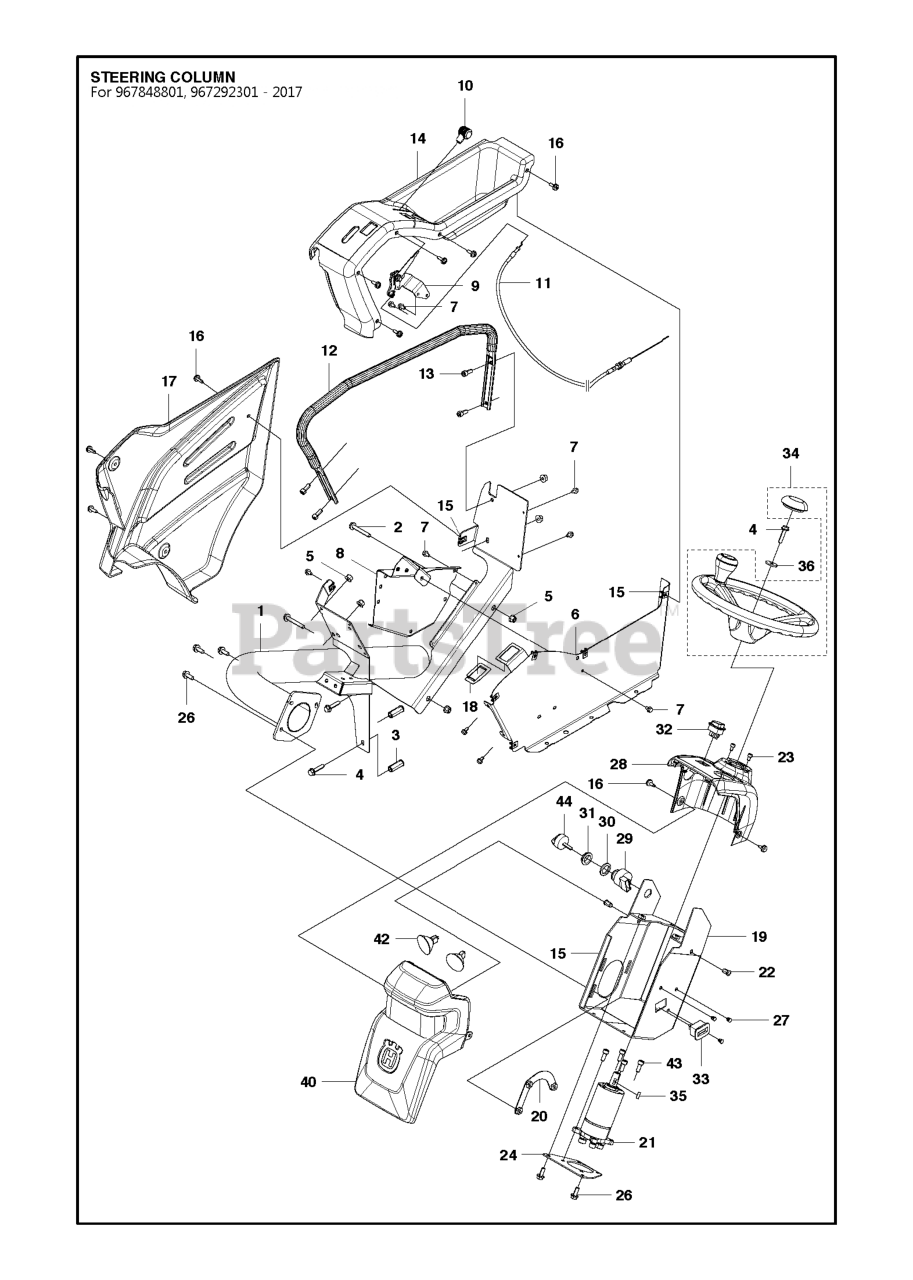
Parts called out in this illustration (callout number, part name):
2	SCREW EHHFM
4	SCREW EHHFM
5	NUT FLANGE
42	LIGHT
